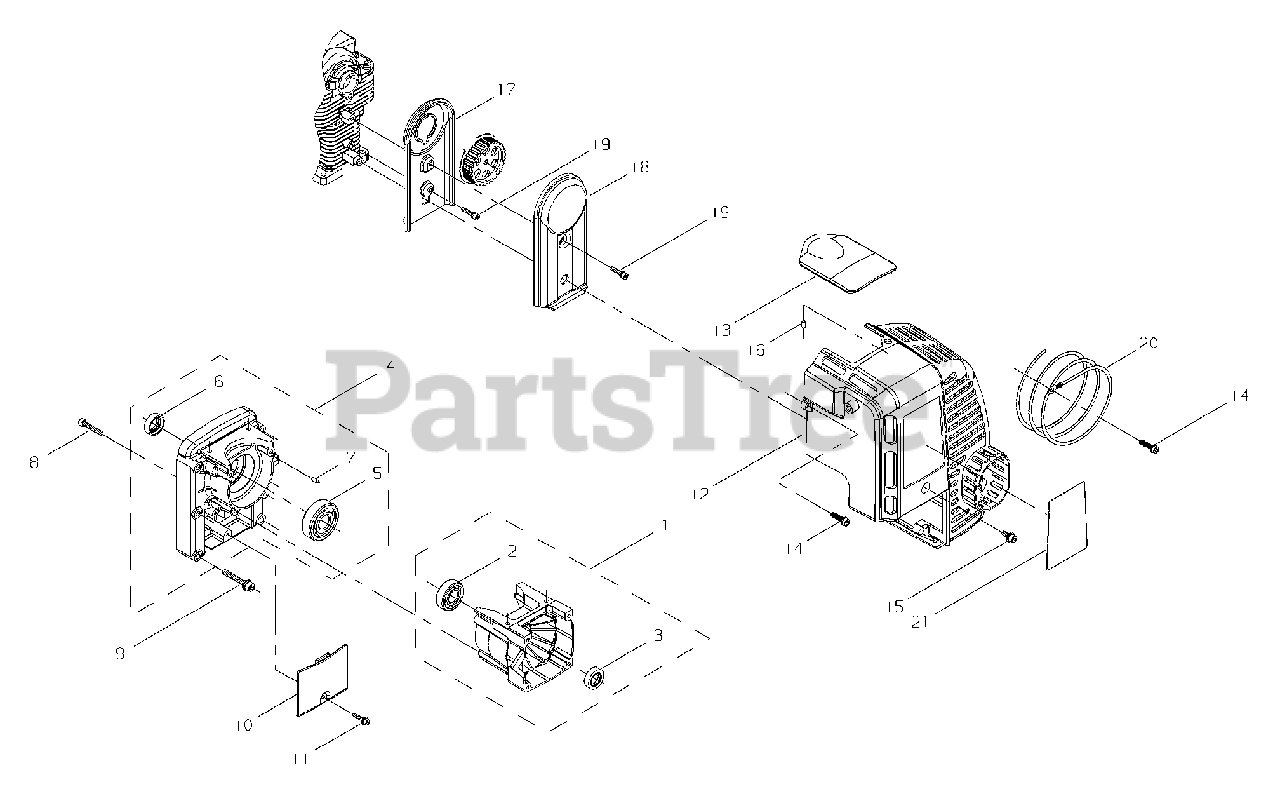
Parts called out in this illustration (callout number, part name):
1	CRANKCASE ASSY - REAR
2	BEARING, BALL - 6202C3
3	SEAL, OIL
4	CRANKCASE ASSY - FRONT
5	BEARING, BALL - 6203C3
6	SEAL, OIL
7	PIN - LOCATING
8	SCREW - 5X30
9	SCREW - 6X40
10	COVER
11	SCREW - 4X20
12	COVER, ENGINE
13	COVER, SPARK PLUG
14	BOLT - 5X20
15	SCREW - 5X14
16	PIN - LOCATING
17	CASE, BELT
18	COVER, BELT
19	SCREW - 5X12
20	LEAD - ANTI-STATIC
21	LABEL - MODEL
